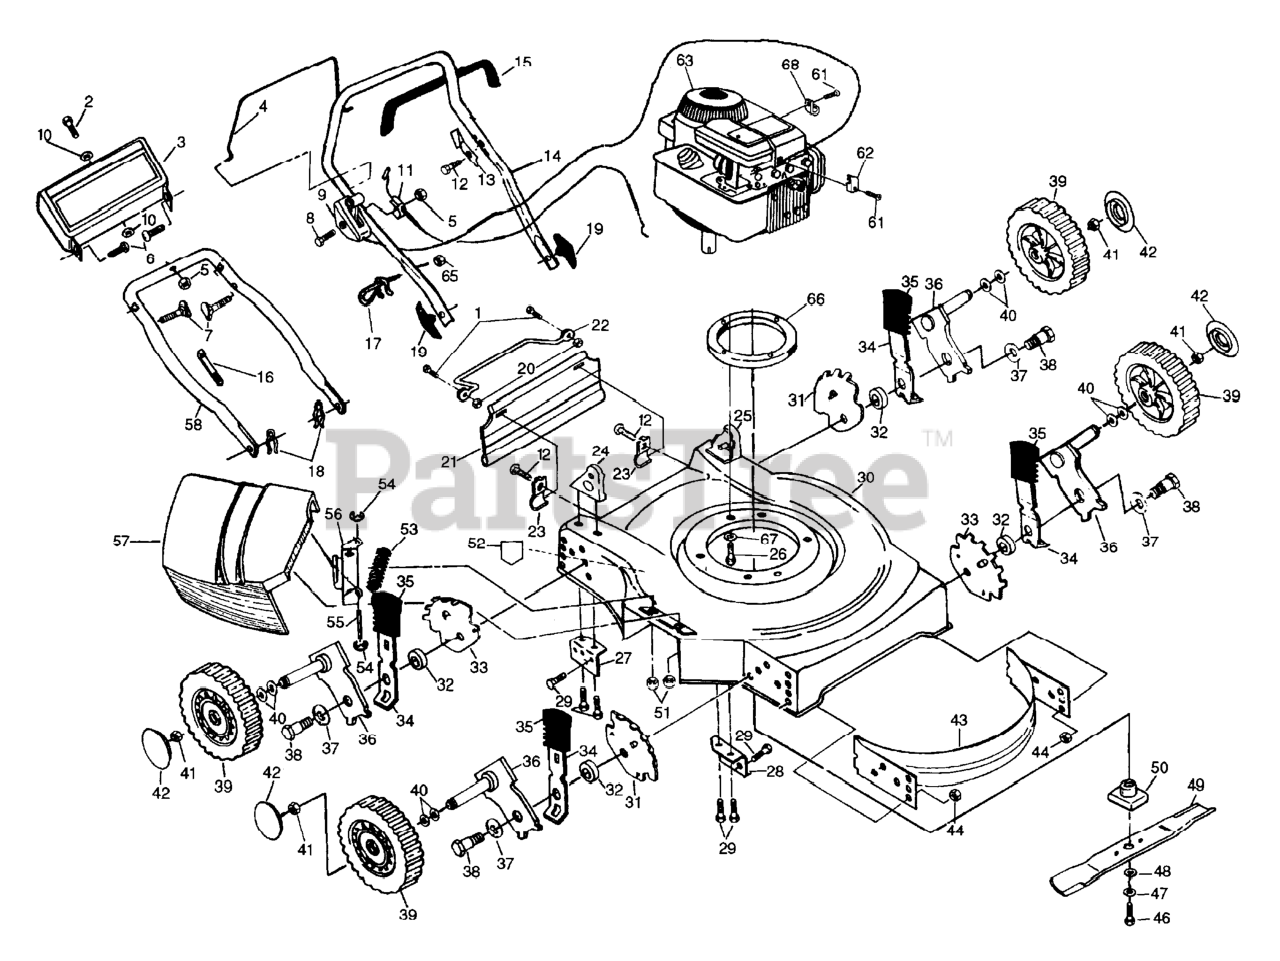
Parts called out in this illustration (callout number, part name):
2	SCREW
3	TRIM PLATE
4	CONTROL BAR/BLACK
5	NUT
7	HANDLE BOLT
8	SCREW 1/4-20 X 2.12
9	THROTTLE CONTROL
11	CABLE.MZR.51.RT.SP./PU.
12	TAPPING SCREW
13	BRACKET UPSTOP
14	UPPER HANDLE
15	HANDLE GRIP
16	TIE GUIDE
17	ROPE GUIDE
18	HAIRPIN COTTER
19	HANDLE KNOB
21	REAR SKIRT
23	BRACKET DEFL PM
24	HANDLE BRKT ASSY RH
25	HANDLE BRKT ASSY LH
27	REPL BY 532 12 52-05
29	SCREW
31	BRACKET.WHL.ADJ.R
32	SPACER PM
33	BRACKET.WHL.ADJ.L
34	SELECTOR SPRING
35	SELECTOR KNOB
36	AXLE ARM AS PM
37	WASHER.BELLEVILLE (3 2 LB)
38	BOLT
39	WHL & TIRE ASSEMBLY
40	WAVE WASHER
41	HEX FLANGE LOCKNT
44	LOCKNUT PM
46	SCREW, HEX HD 3/8-24 X 1-3/8
47	LOCKWASHER
48	WASHER,HARDEN
49	BLADE.20.MULCH.(50DK,6020MD)
50	BLADE ADAPTOR
51	NUT
56	BRACKET PM
57	DISCHARGE GUARD
58	HANDLE, LOWER PM
61	SCREW.HEX.HEAD.WASHER.10-16
62	WASHER
65	NUT
68	GUIDE CLIP PM
